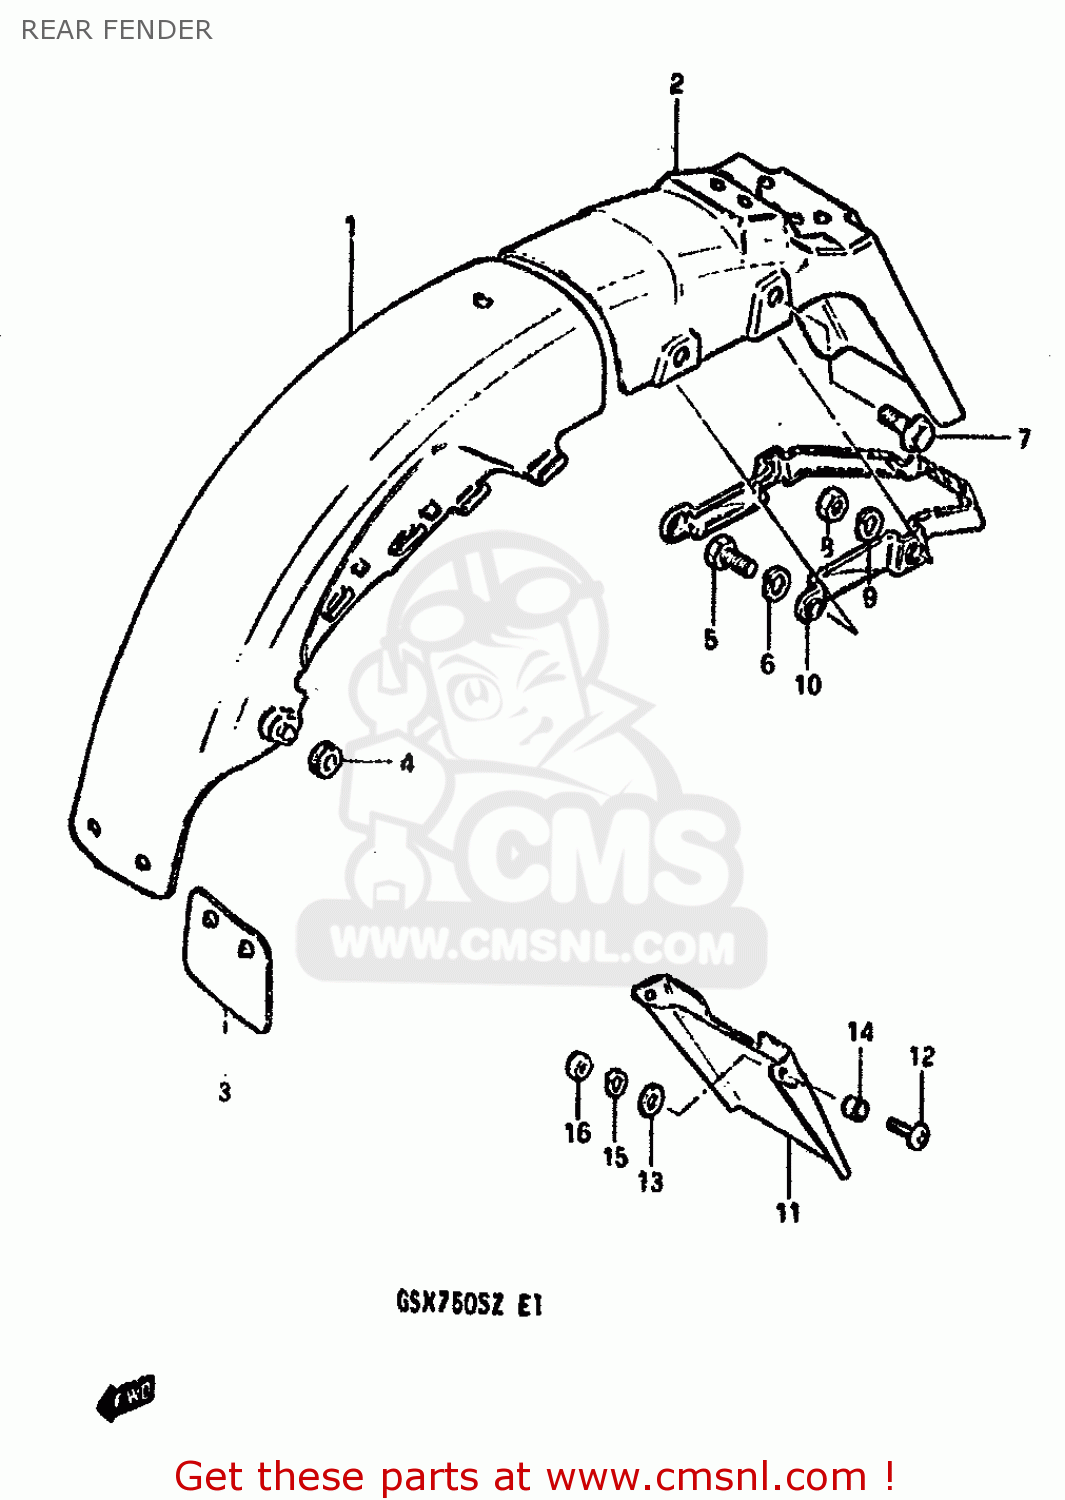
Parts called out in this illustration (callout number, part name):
1	FENDER,REAR
2	FENDER, REAR
3	GUIDE,RR FENDER MUD
4	CUSHION
5	BOLT, UPPER
6	LOCK WASHER
7	BOLT
8	NUT
9	LOCK WASHER
10	REINFORCEMENT,RR FENDER
11	EXTENSION
12	SCREW (6X15)
13	WASHER (6.5X18X1.6)
14	SPACER(6.2X8.3X5.7)
15	LOCK WASHER
16	NUT
